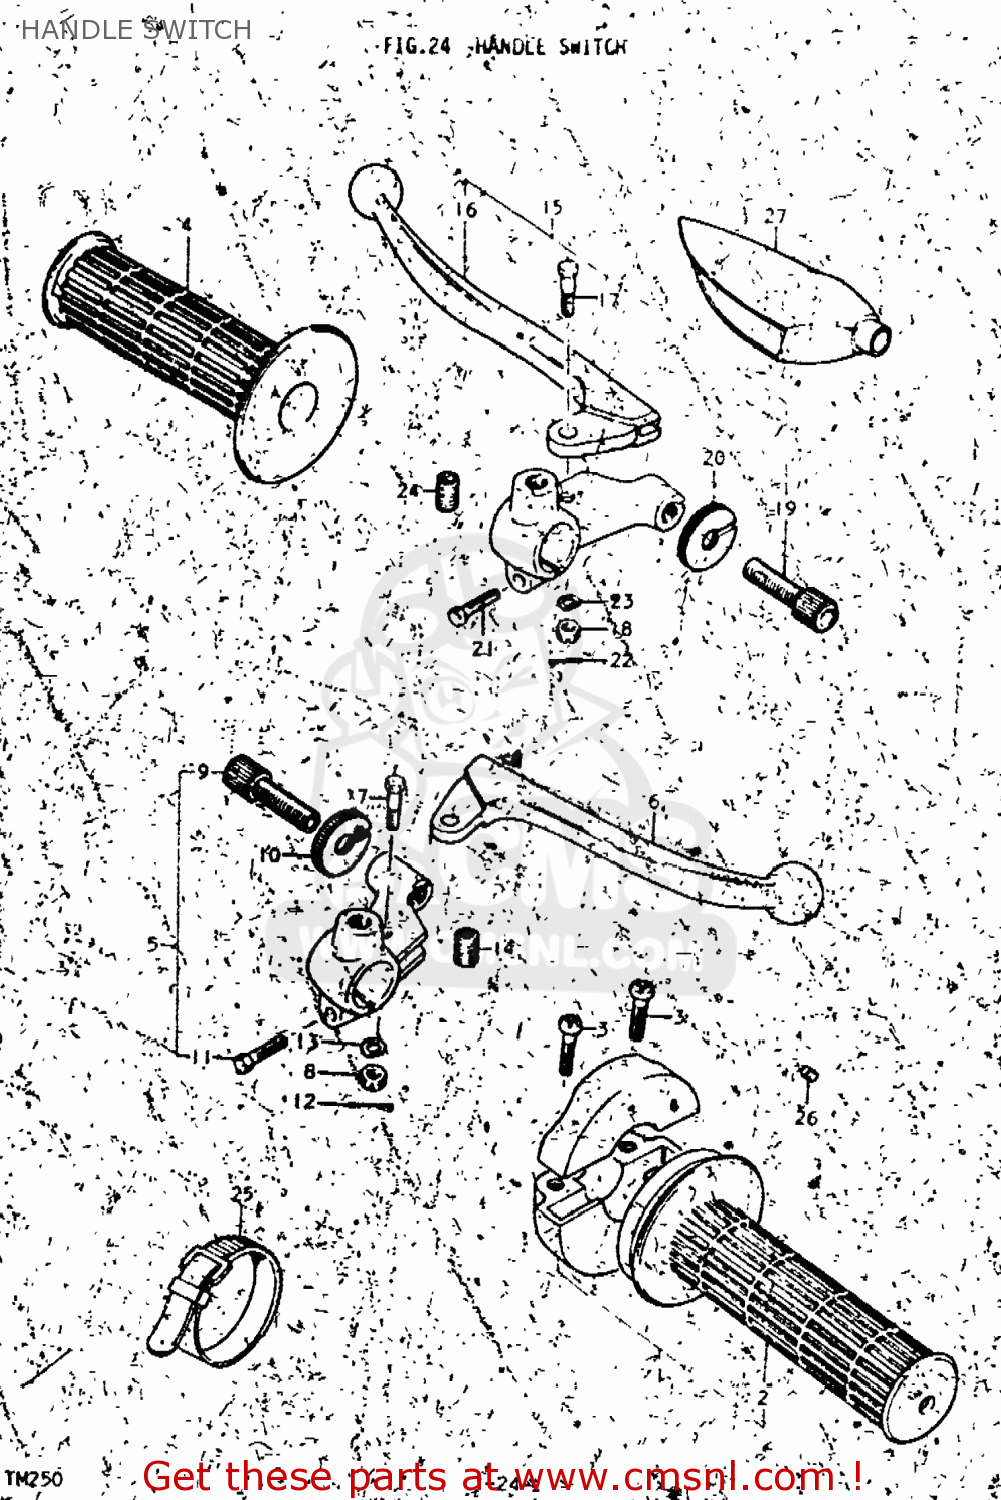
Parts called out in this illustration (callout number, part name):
1	CASE ASSEMBLY,THROTTLE
2	GRIP,THROTTLE
3	SCREW
4	GRIP,LEFT
5	LEVER ASSEMBLY,BRAKE
6	LEVER,BRAKE
7	BOLT,LEVER
8	NUT,LEVER FITTNG
9	ADJUSTER,CABLE
10	NUT,CABLE ADJUSTER
11	BOLT
12	COTTER PIN
13	LOCK WASHER
15	LEVER ASSEMBLY
16	LEVER,CLUTCH
17	BOLT,LEVER
18	NUT,LEVER FITTNG
19	ADJUSTER,CABLE
20	NUT,CABLE ADJUSTER
21	BOLT
22	COTTER PIN
23	LOCK WASHER
25	CLAMP
26	PIECE,THROTTLE END
27	COVER,CLUTCH LEVER
